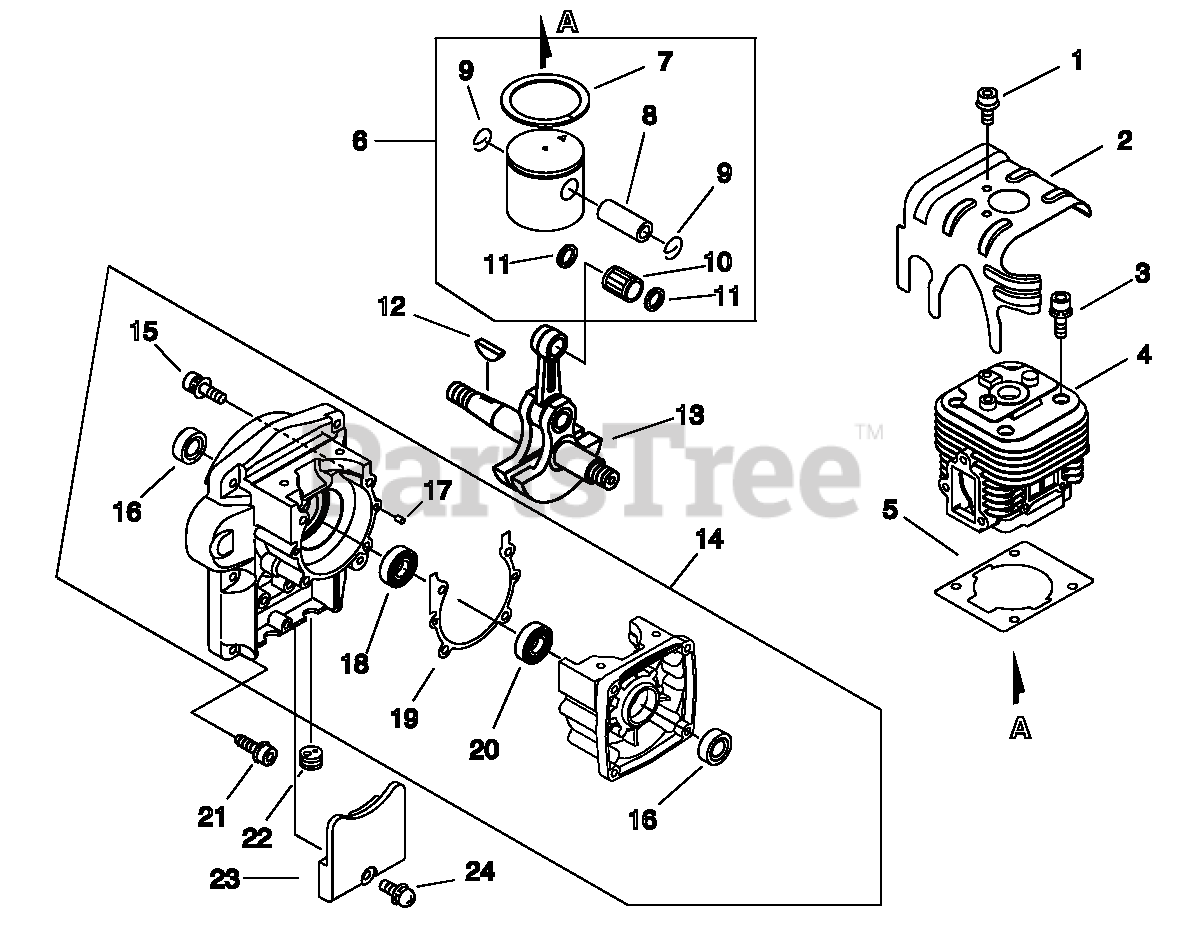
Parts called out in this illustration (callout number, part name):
1	BOLT 5×8
2	COVER, CYLINDER
3	BOLT 5×22
4	CYLINDER
5	GASKET, CYLINDER
6	PISTON KIT
7	RING, PISTON
8	PIN, PISTON
9	RING, SNAP Ø10
9	RING, SNAP 8
10	BEARING, NEEDLE
10	BEARING, NEEDLE 10
11	WASHER, THRUST
12	KEY, WOODRUFF 3×14
13	CRANKSHAFT ASSY
14	CRANKCASE ASSY
14	CRANKCASE KIT
15	BOLT 5×40
16	SEAL, OIL
17	PIN, LOCATING 4×8
18	BEARING, BALL 6302
19	GASKET, CRANKCASE
20	BEARING, BALL 6202
21	SCREW 5×32
23	COVER, DUST
24	SCREW 5×18
